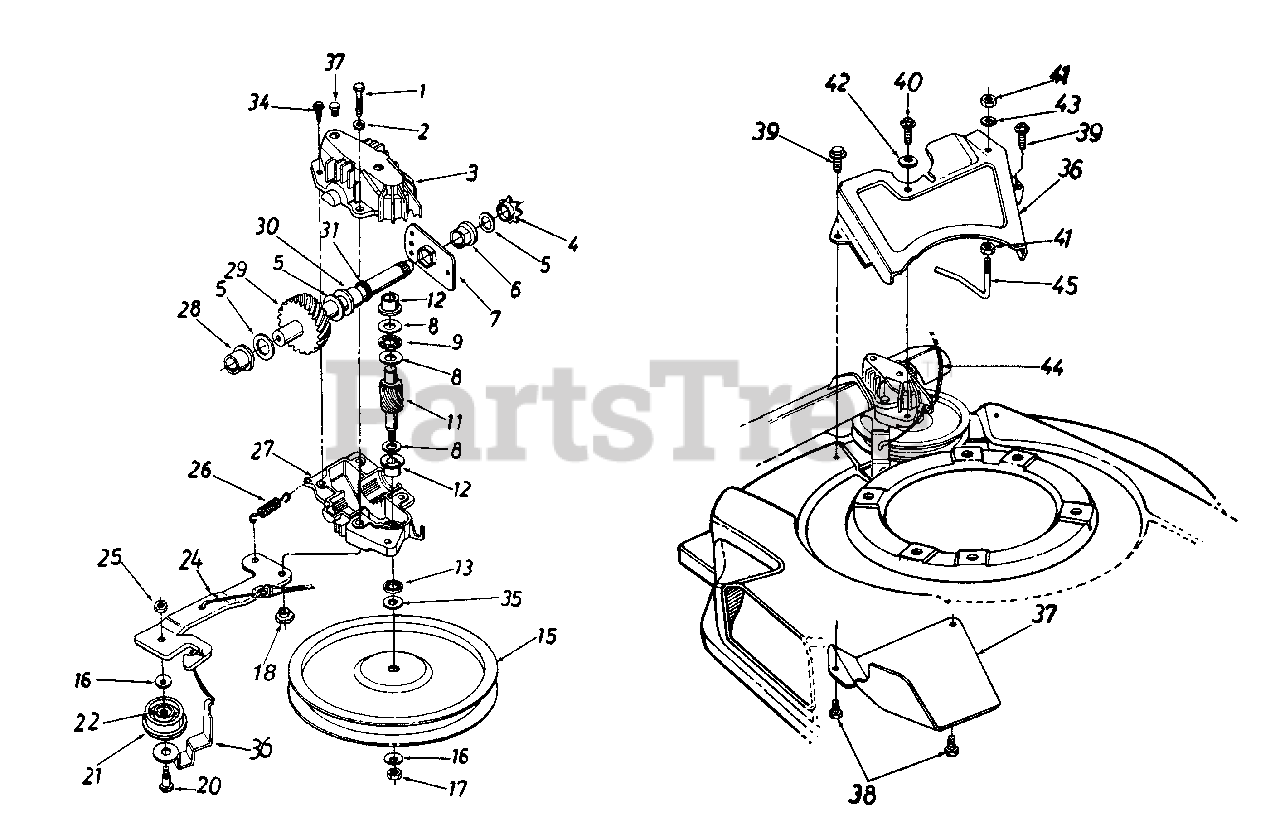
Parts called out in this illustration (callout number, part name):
1	Hex Patch Bolt 1/4-20 x 1.25" Lg.
2	L-Wash. 1/4" I.D.
3	Upper Hsg. Half
4	#48 Sprocket 7 Tooth x 1/2 Pitch
5	Fl-Wash. 5/8" I.D. x .030
6	Hex Flange Brg. .631" I.D.
8	Thrust Wash. .382" I.D. x .70" O.D.
9	Thrust Bearing .375" I.D. x .812" O.D.
11	11 Tooth Helical Gear
12	Flange Bearing
13	Oil Seal
15	Fl-Pulley 5.06" I.D.
16	Bell-Wash. .265" I.D. x .75"
17	Hex Nut 1/4-28 L.H.Thd.
18	Shld. Spacer .375" Dia. x .170
20	Shld. Bolt .375" Dia. x .40"
21	Fl-Idler Plastic 1.50" Dia.
22	Needle Brg. .375" x .375"
24	Idler Brk't. Ass'y.
25	Hex Patch L-Nut 1/4-28 Thd.
26	Extension Spring 1.12" Lg.
27	Lower Hsg. Half
28	Flange Bearing .56 Dia.
29	Shaft Ass'y.
30	Flange Bearing .629 Dia.
31	Oil Seal .625 Dia.
34	Hex B-Tap Scr. #10 x .62"
35	Hex Washer .26" x .88"
39	Hex AB-Tap Scr. 1/4 x .50" Lg.
40	Hex B-Tap Scr. 1/4 x .62" Lg.
41	Hex Nut 1/4-20 Thd.
42	Bell-Wash. .265" I.D. x .75"
43	L-Wash. 1/4" I.D.
44	S.R Cable-48" Lg.
45	S.P. Belt Guard
